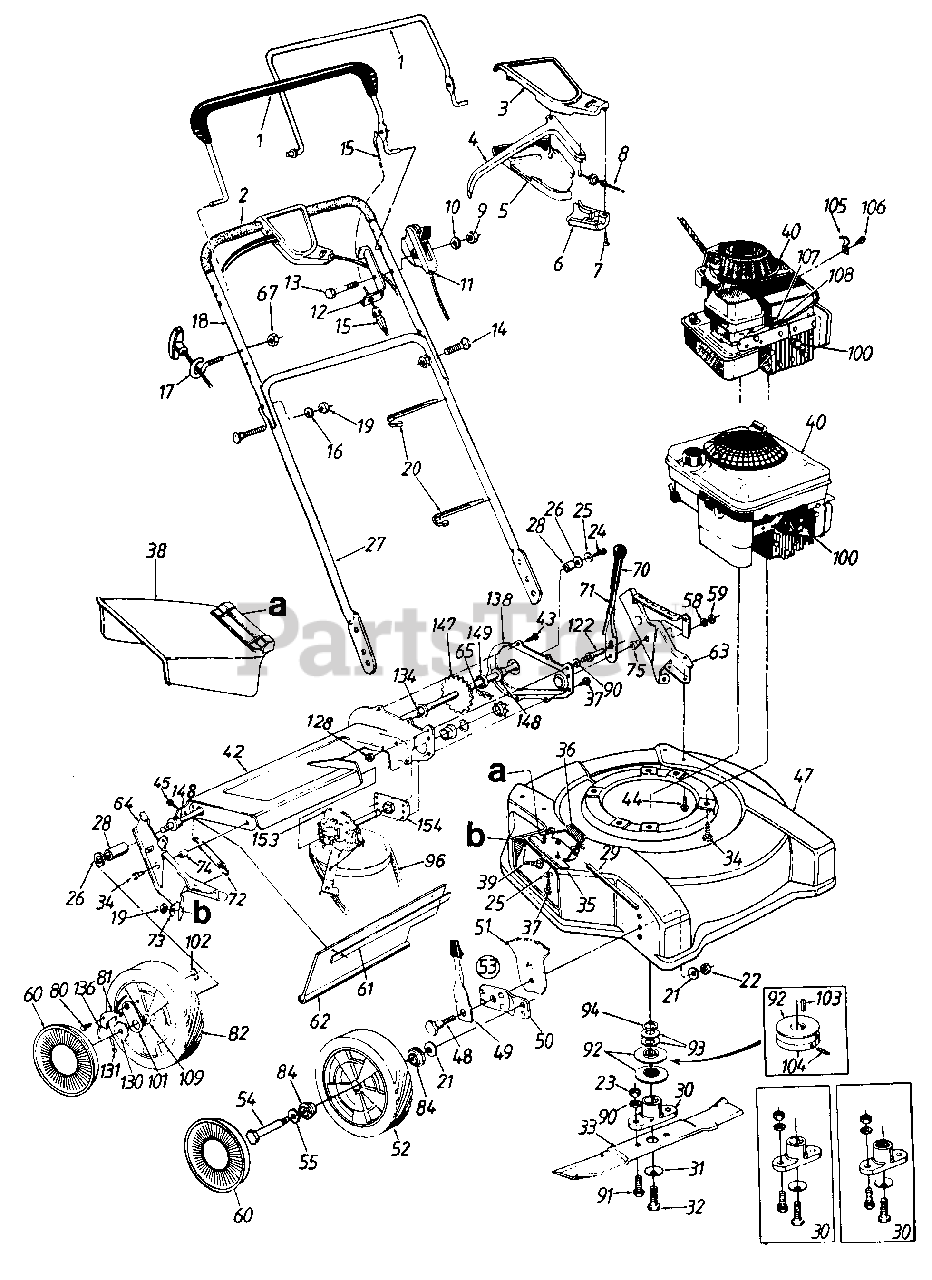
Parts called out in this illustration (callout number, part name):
1	Control Handle Ass'y.
2	Foam Grip
3	Upper-S.P. Control Cover
4	Control Lever
5	Lower-S.P. Control Cover
6	S.P. Control Cover
7	Fl-'C"-Sunk Hd. Tap Scr. #10 x .75" Lg.
8	S.P. Adj. Cable-44" Lg.
9	Hex Nut 1/4-20 Thd.
10	Spr. Wash. .265" I.D. x .562"
11	Throttle Control Comp.-56.6"
12	Cable Mtg. Brkt.
13	Hex Bolt 1/4-20 x 1.85" Lg.
14	Curved Carr. Bolt 5/16-18 x 1.38"
15	Control Cable 43" Lg.
16	L-Wash. 5/16" I.D.
17	Rope Guide Bolt
18	Upper Handle
19	Hex Nut 5/16-18 Thd.
20	Cable Tie
21	Bell-Wash. .38" I.D. x .88"
22	Hex Nut 3/8-16 Thd.
23	Hex Nut 3/8-24 Thd.
24	Hex Bolt 1/4-20 x .62" Lg. Grade 5)
25	Bell-Wash. 1/4" I.D.
26	Fl-Wash. .531" I.D. x .93"
27	Lower Handle
28	Spacer .513" I.D. x .703"
29	Hinge Pin
30	Blade Adapter Kit
31	Bell-Wash. .39" I.D.
32	Hex Bolt 3/8-24 x 1.5" Lg.
33	22" Blade
34	Hex L-Wash. Hd. Scr. 3/8-16 x 1.0" Lg.
35	Adapter Plate
36	Torsion Spring
37	Hex Self-Tap Scr. 1/4-20 x .5"
38	Chute Deflector Ass'y.
39	Carriage Bolt 5/16-18 x .62" Lg.
40	Engine
44	Hex Wash. Hd. B-Tap Scr. 5/16-18
45	Hex AB-Tap Scr. 1/4 x .62"
49	Spring Lever Ass'y. w/Knob
51	Height Adj. Plate
52	Wheel Ass'y. Comp.
53	Height Adj. Ass'y. Comp.-R.H.
54	Shld. Bolt .498" Dia. x 1.45"
55	Wave Wash. .53" I.D. x .78"
58	Fl-Wash. .385" I.D. x .87"
59	Hex Patch L-Nut 3/8-24 Thd.
60	Hub Cap
61	Retaining Strip
62	Rear Flap
63	L.H. Handle Wheel Brkt. Ass'y.
64	R.H. Handle Wheel Brkt. Ass'y.
65	#48 Chain .5" Pitch x 30 Links
67	Hex L-Nut '/4-20 Thd.
71	Height Adj. Lever
72	Ext. Spring .5" O.D. x 3.8" Lg.
73	Bell-Wash. 5/16" I.D.
74	Spacer .383" I.D. x .503"
75	Shld. Spacer .5" Dia.
80	Shld. Scr. .342" Dia. x .268"
81	Pawl
82	Wheel Ass'y. Comp.
84	Ball Bearing 1/2" I.D.
90	L-Wash. 3/8" I.D.
91	Hex Bolt 3/8-24 x 1.0" Lg.
92	Keyed Pulley
93	Bell-Wash. 1.01" I D
94	Crankshaft Spacertt
96	"V"-Belt
100	Spark Plug Boot
101	Pawl Plate
102	Weld Nut 1/4-20 Thd.
103	Sq. Key 3116" x 3/4" Lg.
104	Set Scr. #10-32 x .25" Lg.
105	Cable Clamp
106	Hex B-Tap Scr. #10 x .38" Lg.
107	Cable Clamp
108	Hex B-Tap Scr. #10 x .5" Lg.
109	Sleeve Brg. 1/2" I.D.
122	Shld. Pin 3/8-24 x 1.43" Lg.
128	Hex Jam Nut 3/8-24 Thd.
130	Ratchet Wheel 1.62" O.D.
131	Cotter Pin 1/8" Dia.
134	Hex Flange Bearing
136	Spring-Nylon
148	Hex Flange Bearing
149	Fl-Wash. .531" I.D. x .93"
153	Transmission Comp.
17055B-0637	AXLE ASSY-CHAIN - POWDER BLACK (0637)
17055B-0638	AXLE ASSY-CHAIN - MTD/TROY-BILT RED (0638)
17055B-0665	AXLE ASSY-CHAIN - YARDMAN GREEN (0665)
